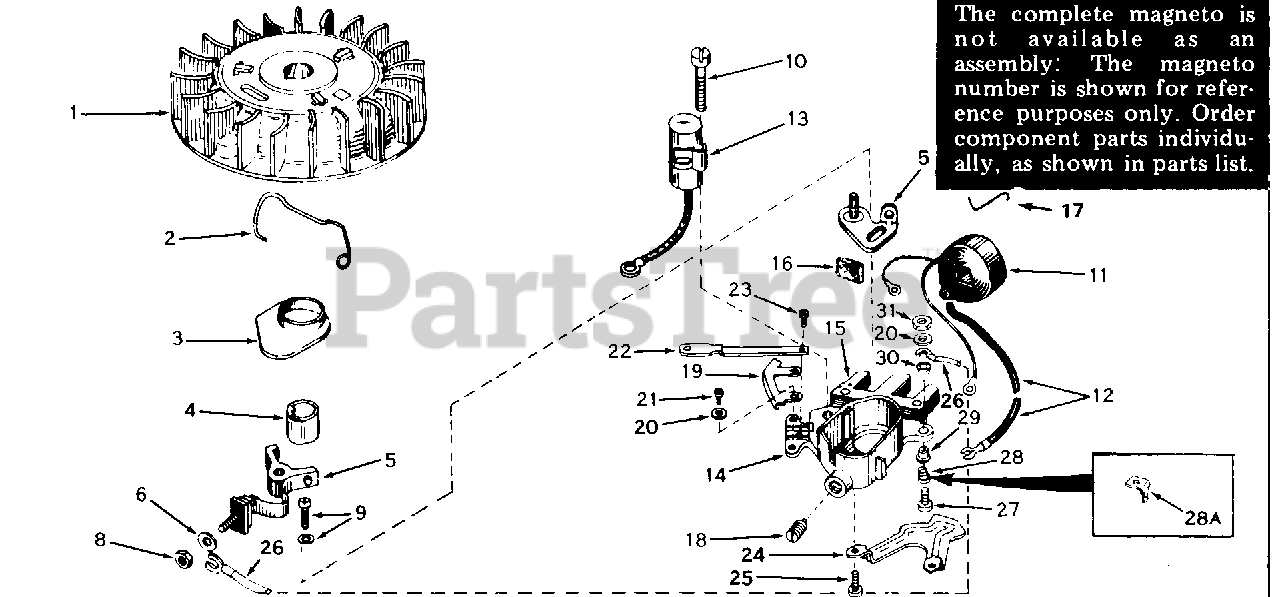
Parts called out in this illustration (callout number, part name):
1	Flywheel
2	Spring, Breaker box cover
3	Cover, Breaker box
4	Cam, Breaker
5	Breaker Points (also available in Pac kaged Part #740037B)
6	Washer, Terminal
8	Nut, Terminal
9	Screw & Washer, Breaker
10	Screw, Condenser
11	Coil Assy., (Incl. 12)
12	Wire, Lead
13	Condenser
14	Core & Plate
15	Stator Assy. Incl. 2, 5 thru 14, 16 t hru 31
16	Felt, Cam wiper
17	Clip, Coil locking
18	Screw Assy., Friction
19	Cam, Throttle
21	Screw, 6-32 x 3/8"
22	Lever, Control
23	Screw, 10-24 x 3/8"
25	Screw, 6-32 x 3/8"
26	Wire, Cut off
27	Screw, 6-32 x 3/4"
28	Spring (Use as required)
29	Washer, Insulating
30	Washer, Insulating
31	Nut, Hex, 6-32
